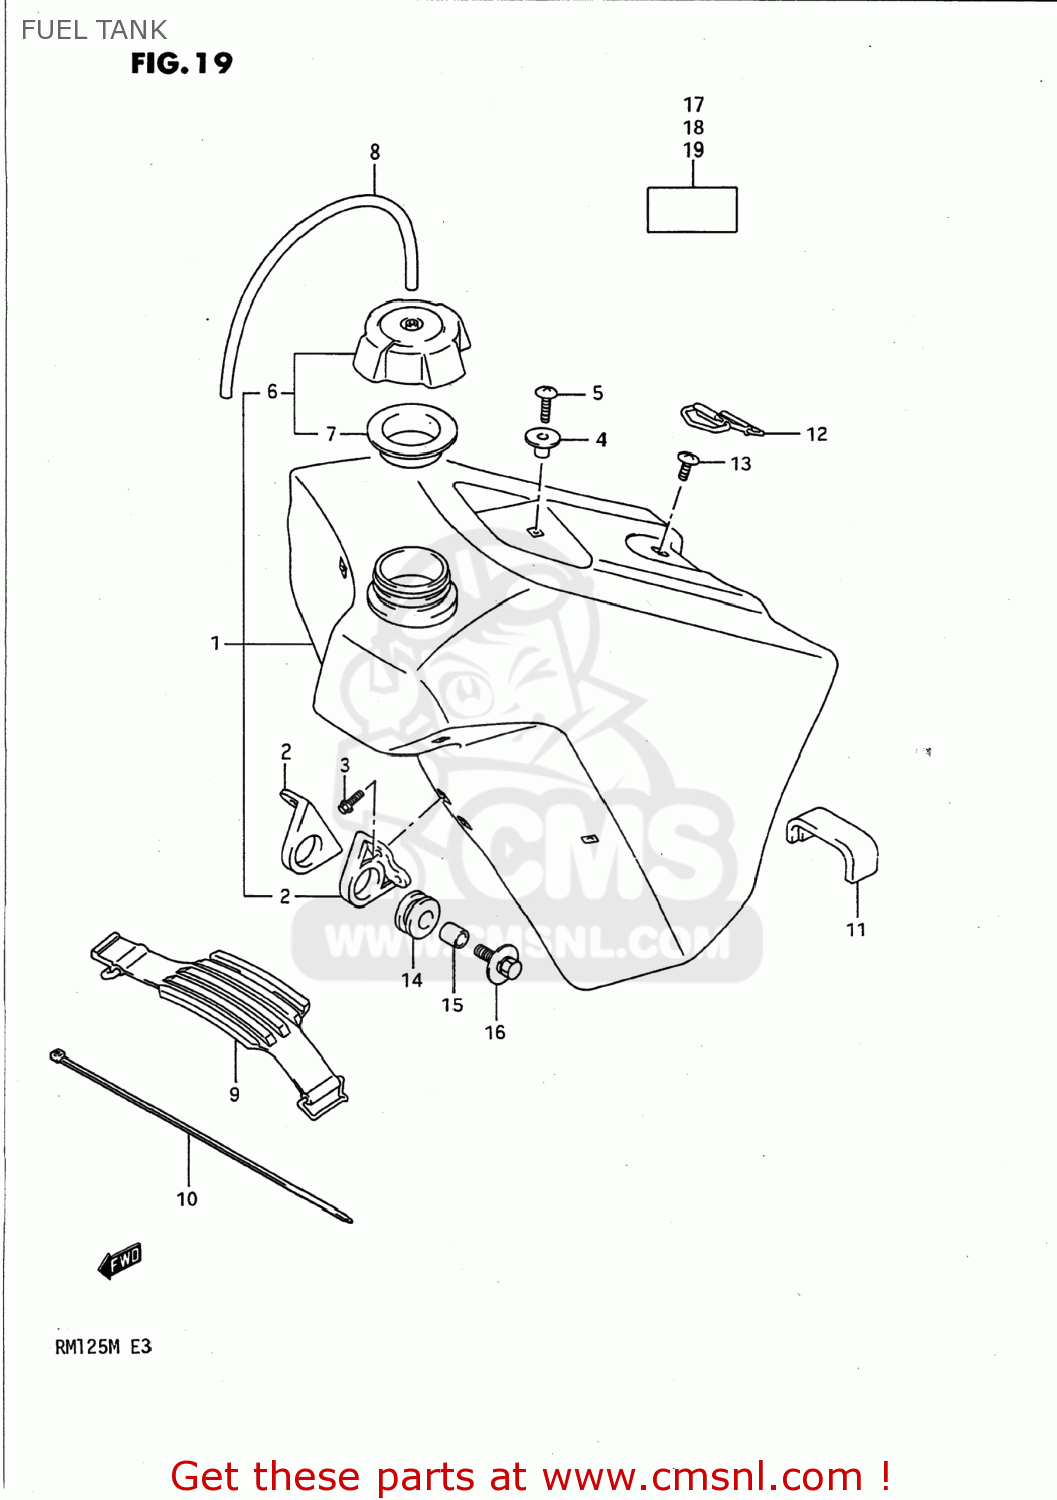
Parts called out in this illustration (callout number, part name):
1	TANK ASSEMBLY,FUEL
2	BRACKET,FUEL TANK FR
3	BOLT
4	HOOK,SEAT,FRONT
5	SCREW
6	CAP SET,FUEL TANK
7	GASKET,CAP (NAS)
8	HOSE
9	CUSHION,FUEL TANK NO.1
10	CLAMP
11	CUSHION,FUEL TANK,UPPER
12	BAND,FUEL TANK RR
13	SCREW
14	CUSHION
15	BOLT(8X30)
16	SPACER (8.8X12X13.5)
17	LABEL,WARNING
18	LABEL (WARNING)
19	LABEL (WARNING)
